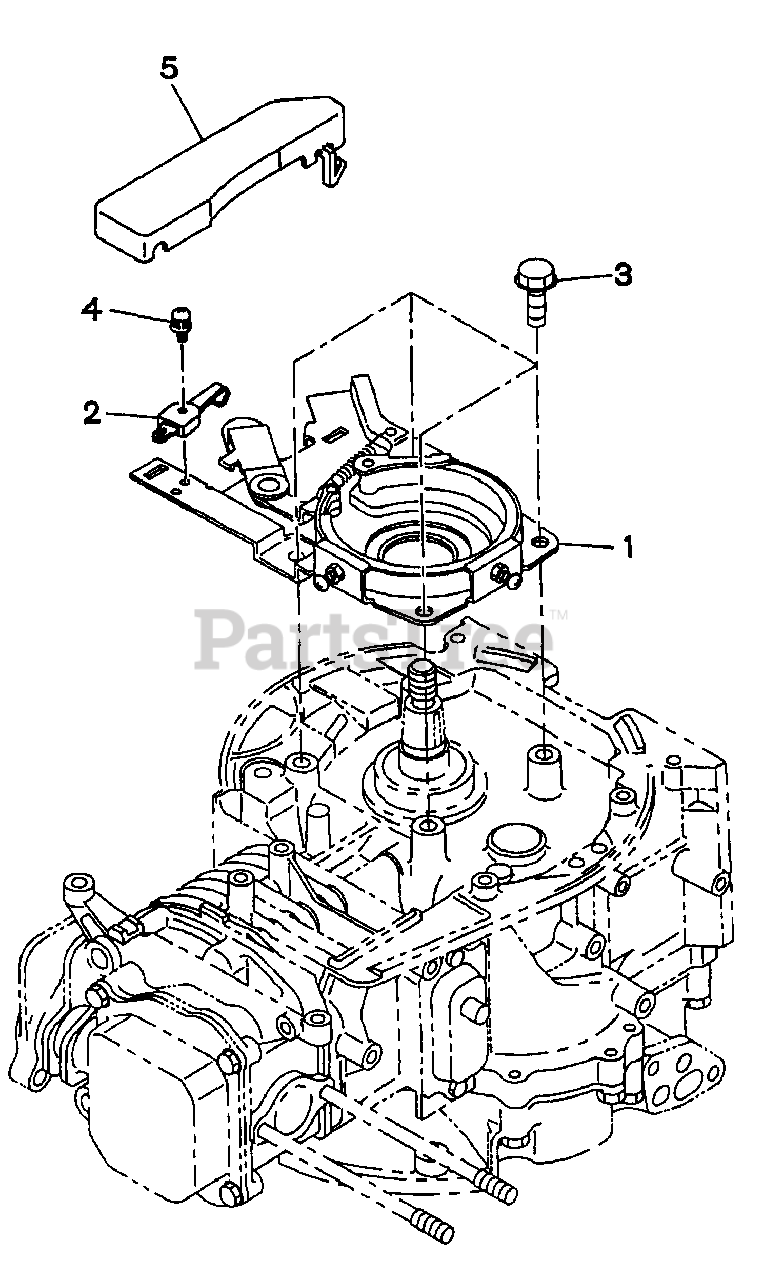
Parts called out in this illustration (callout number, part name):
1	BRAKE ASS'Y
2	STOP SWITCH
3	FLANGE BOLT
4	SCREW and WASHER ASS'Y
5	COVER, stop switch (Classic Steel)
